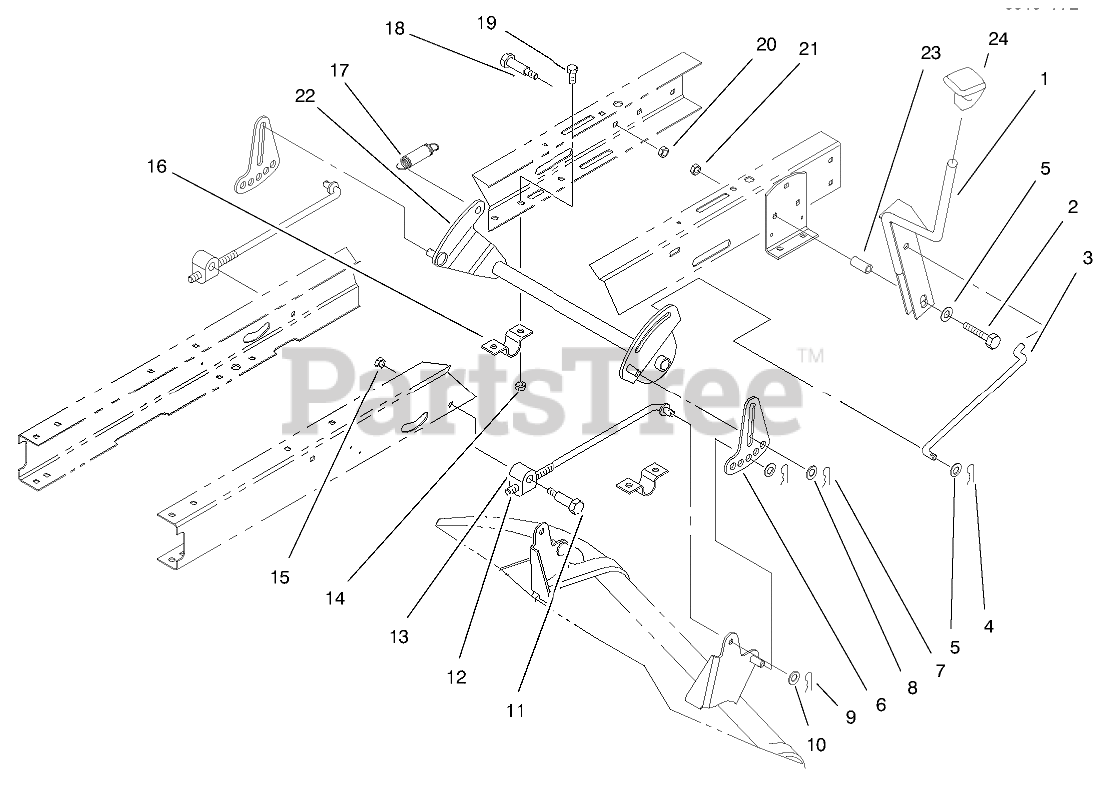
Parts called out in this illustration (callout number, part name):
1	HOC LEVER ASM
2	SCREW-HH
3	LINK-HOC
4	PIN-COTTER
5	WASHER-FLAT
6	LINK-ADJUSTING, HOC
7	PIN-COTTER
8	WASHER-HARDENED
9	PIN-COTTER
10	WASHER-FLAT
11	SCREW-SHOULDER, HH
12	ROD-HANGER, REAR
13	TRUNNION-HOC
14	NUT-LOCK, NI
15	NUT-LOCK, NI
16	CLAMP-PIVOT, HOC
17	SPRING-EXTENSION
18	SCREW-SHOULDER, HH
19	SCREW-HH
20	NUT-LOCK, NI
21	NUT-LOCK, NI
22	PIVOT ASM
23	SPACER
24	KNOB-SHIFT
